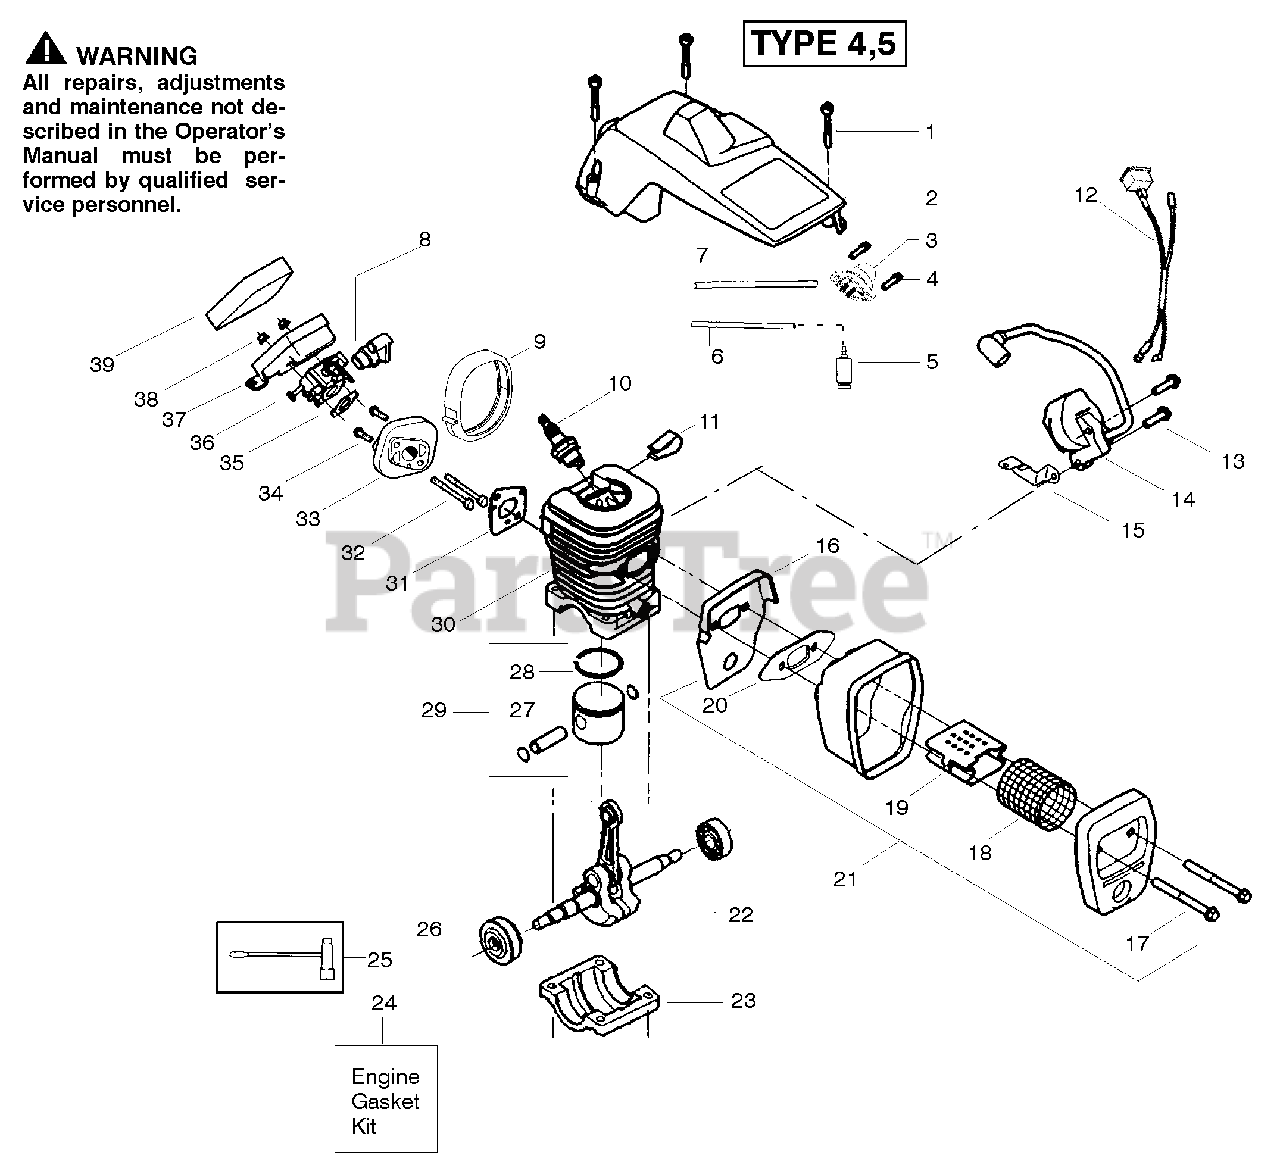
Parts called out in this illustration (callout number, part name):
2	Shield-Cylinder
3	Assy-Air Purge
5	Assy-Fuel Pick-up
6	Kit-Line Purge/Carb. (Small Dia)
7	Kit-Line Purge/Tank (large line)
8	Grommet-Carb Adjust.
9	Seal-Carb Adapter
10	Spark Plug (RCJ-7Y)
11	Clip-High Tension Lead
12	Assy-Wire Harness
14	Module-Ignition
15	Strap-Ground
16	Back Plate-Muffler
18	Screen-Spark
19	Diffuser-Muffler
20	Gasket-Muffler(kit)
21	Assy-Muffler
22	Assy-Crankshaft
23	Cap-Crankcase
24	Kit-Engine Gasket
25	Scrench
26	Assy-Seal & Bearing
27	Retainer - Piston Pin
28	Ring-Piston
29	Kit-Piston
30	Kit-Cylinder
31	Gasket-Adapter(kit)
33	Adapter-Carb.
35	Carb. Gasket(kit)
36	Kit-Carburetor (WT-625)
37	Housing-Air Filter
39	Air Filter - Foam
